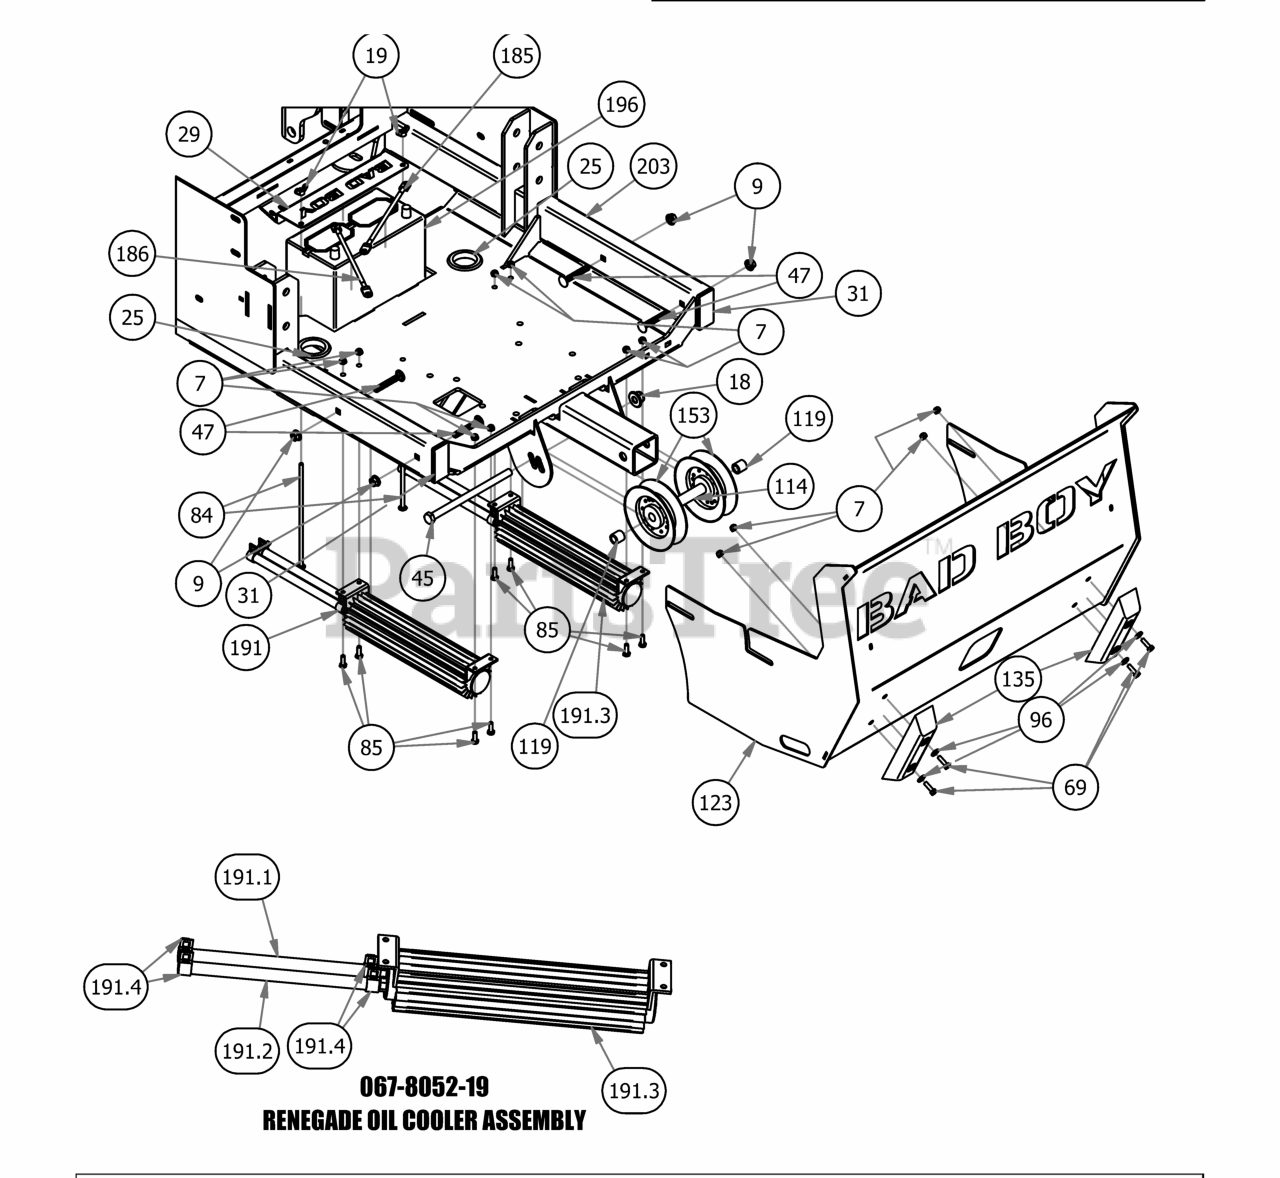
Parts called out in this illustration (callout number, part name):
7	1/4-20 Hex flang lock nut
9	3/8-16 NYLON INSERT FLANGE LOCKNUT (GR.F) ZINC
18	1/2-13 NYLON INSERT FLANGE LOCKNUT ZINC
19	1/4" Wing Nut
29	2019 Horizontal Battery Hold Down Cover
45	1/2" x 8 1/2 GR 5 Hex Bolt
47	3/8" x 2 1/2" Carriage Bolt
69	1/4-20 x 1-1/4 GR 5 Hex Bolt
84	1/4" x 1" Carriage Bolt
85	1/4" x 3/4" Hex Bolt
96	1/4" Flat Washer
114	2019 Pulley Spacer .75 x .5 x 4.375
119	Spacer 3/4 OD x 1/2 ID x 3\4 Length
123	2019 Horizontal Suspension Rear Cover
135	8" Rubber Bumper
153	2019 Outlaw Horizontal Rear V Pulley
185	Red Battery Cable - Diesel
186	Black Battery Cable - Diesel
191	Renegade Oil Cooler Assembly
191.1	3/8" Clear Hose
191.2	3/8" Clear Hose
191.3	2019 12" Oil Cooler With Fittings
191.4	3/8" Hose Clamp
196	Battery - Diesel/Renegade Models PF-516
203	2019 Horizontal Gas Frame
